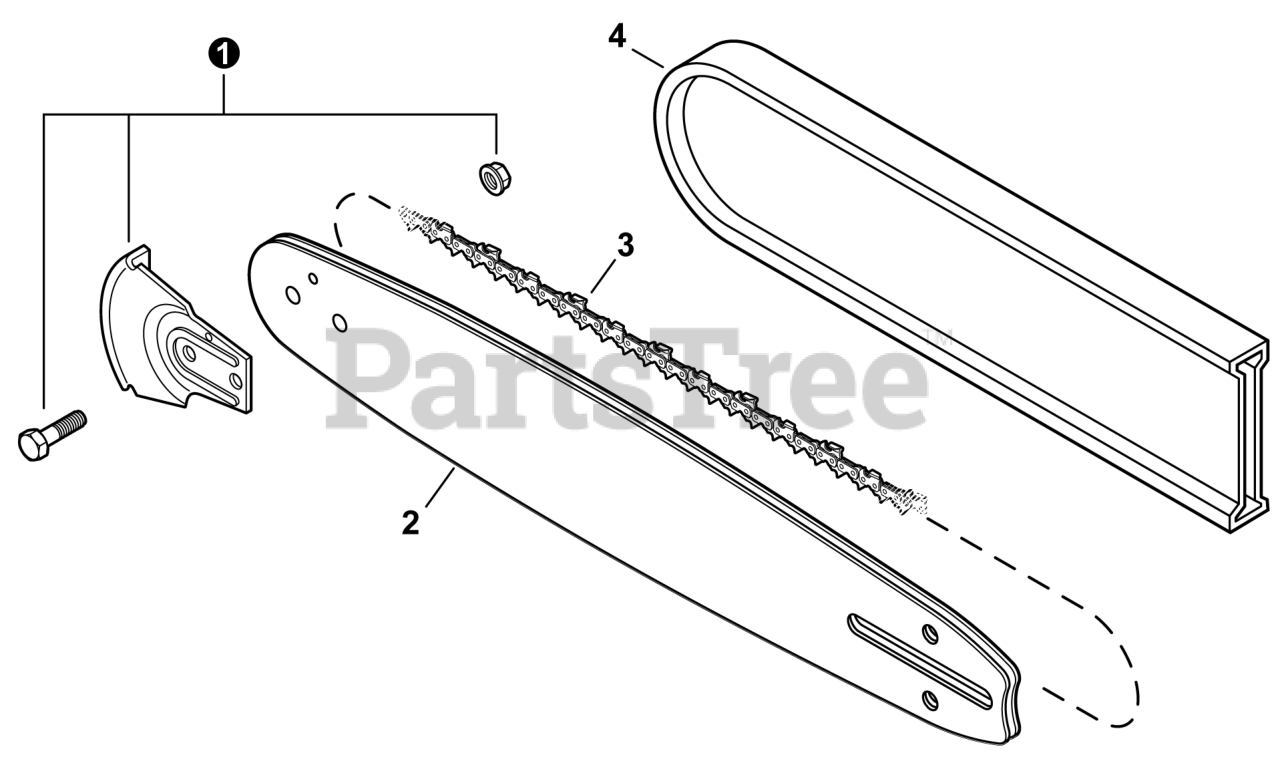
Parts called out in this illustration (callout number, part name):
1	KICK GUARD KIT
2	GUIDE BAR, 12" MICRO-LITE PRO
2	GUIDE BAR, 12" DOUBLE-GUARD
3	SAW CHAIN 12" - MICRO-LITE
3	SAW CHAIN 12"
4	SCABBARD 12"-20"
